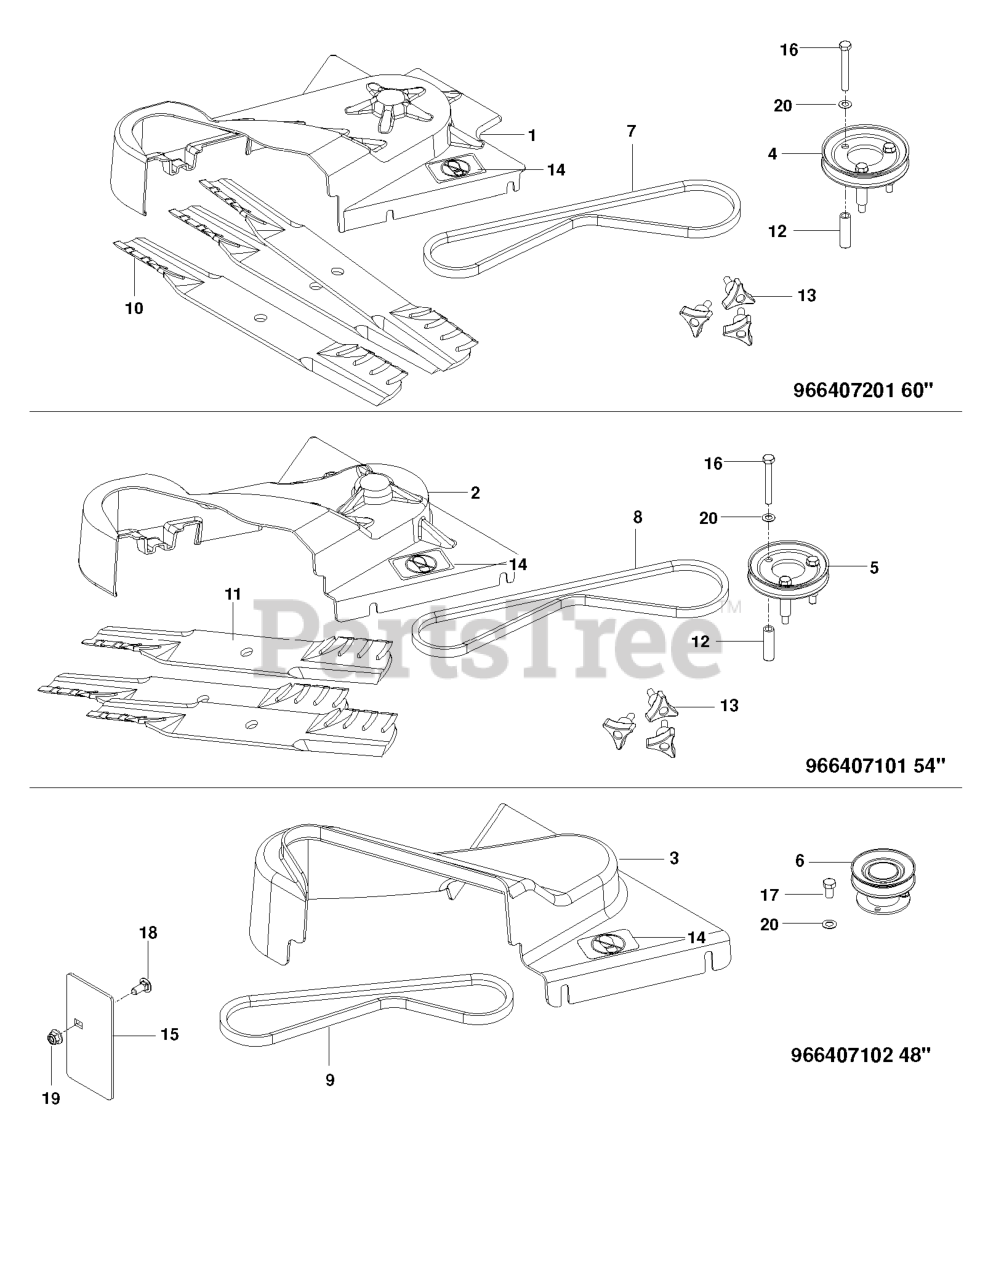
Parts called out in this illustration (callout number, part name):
1	SHIELD, LOWER, 60"
2	SHIELD, LOWER, 54"
3	SHEILD BELT BLOWER 48 BLK
4	PULLEY, DRIVE, 60"
5	PULLEY, DRIVE, 54"
6	PULLEY.DRIVE.48"
7	BELT, BLOWER
8	BELT, DRIVE RAKE/SLICER DFS
9	BELT.BLOWER
10	BLADE, 21" GATOR, 1.25 LIFT
11	BLADE, 19" GATOR, 1.25" LIFT
12	SPACER, PULLEY
13	KNOB W/STUD
14	DECAL, NO STEP
15	PLATE BLOCK OFF
16	BOLT 5/16C X 2 1/2
17	HCS 5/16-18 X 5/8 GR 5 ZD
18	BOLT 5/16C X 3/4" CARRIAGE
19	5/16-18 NYLOC FLANGE NUT
20	WASH 5/16 DISC SPRING ZD
